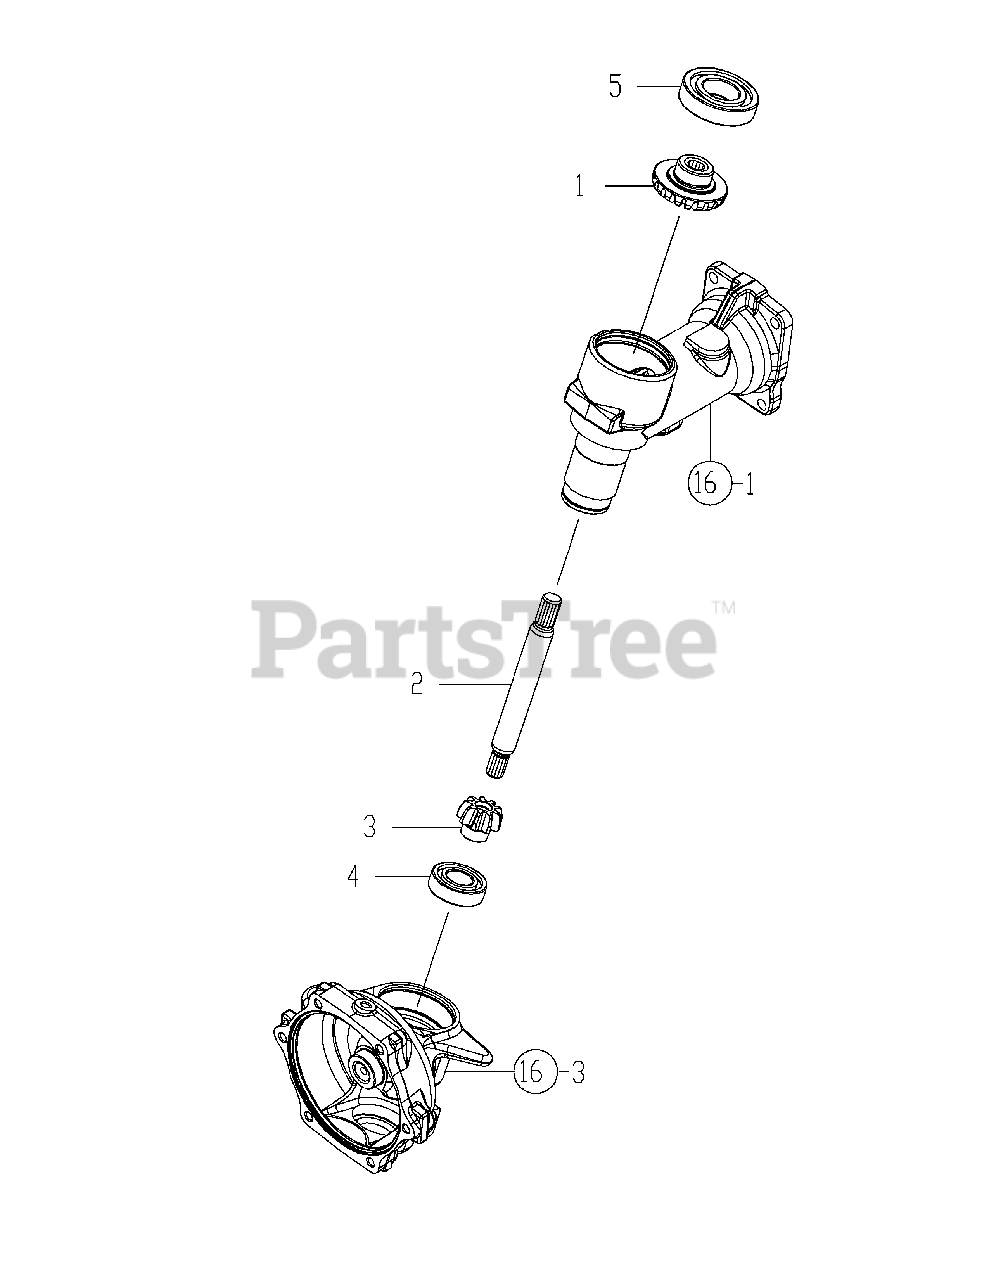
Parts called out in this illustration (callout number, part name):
1	GEAR, 20T,BEVEL
3	PINION F,FINAL
4	BEARING, 6205 NTN
